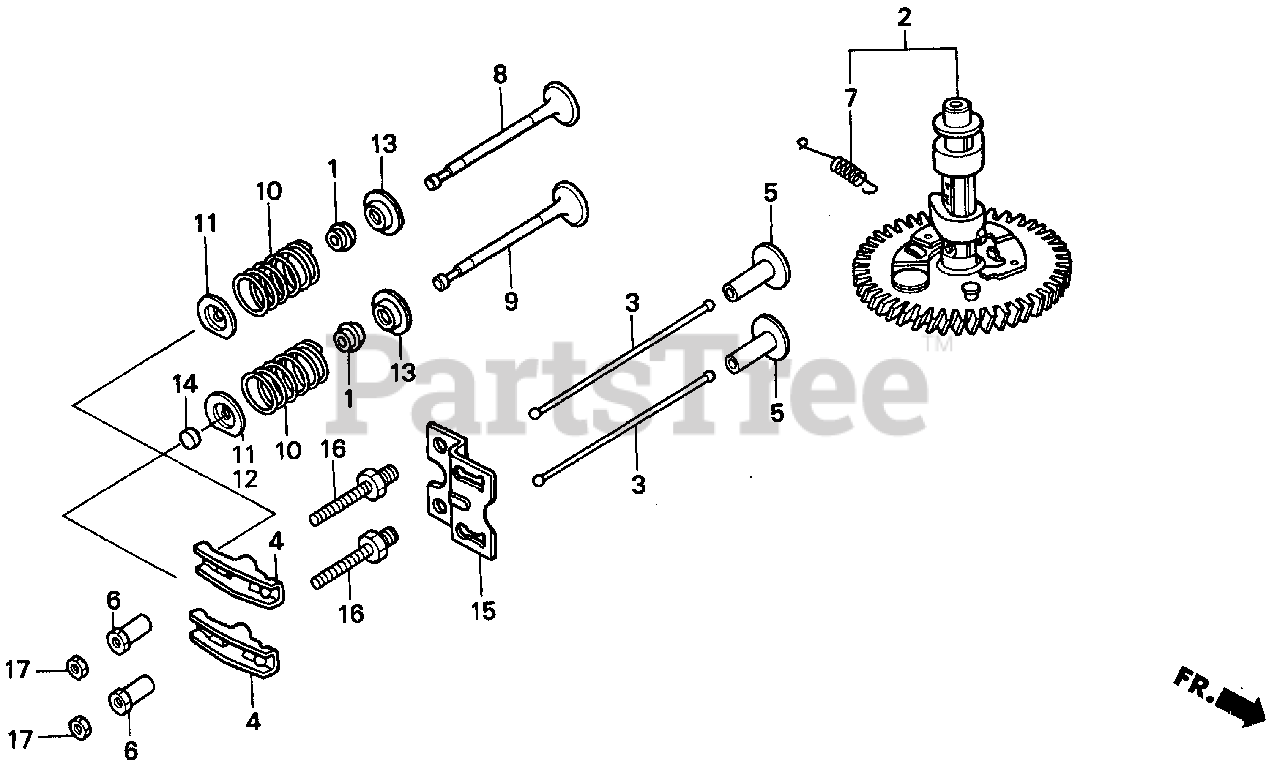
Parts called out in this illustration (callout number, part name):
1	SEAL, VALVE STEM
2	CAMSHAFT ASSY.
3	ROD, PUSH
4	ARM, VALVE ROCKER
5	LIFTER, VALVE
6	PIVOT, ROCKER ARM
7	SPRING, WEIGHT RETURN
8	VALVE, IN.
9	VALVE, EX. (STELITE)
10	SPRING, VALVE
11	RETAINER, IN. VALVE SPRING
13	SEAT, VALVE SPRING
15	GUIDE, PUSH ROD
16	BOLT, PIVOT (8MM)
17	NUT, PIVOT ADJ.
